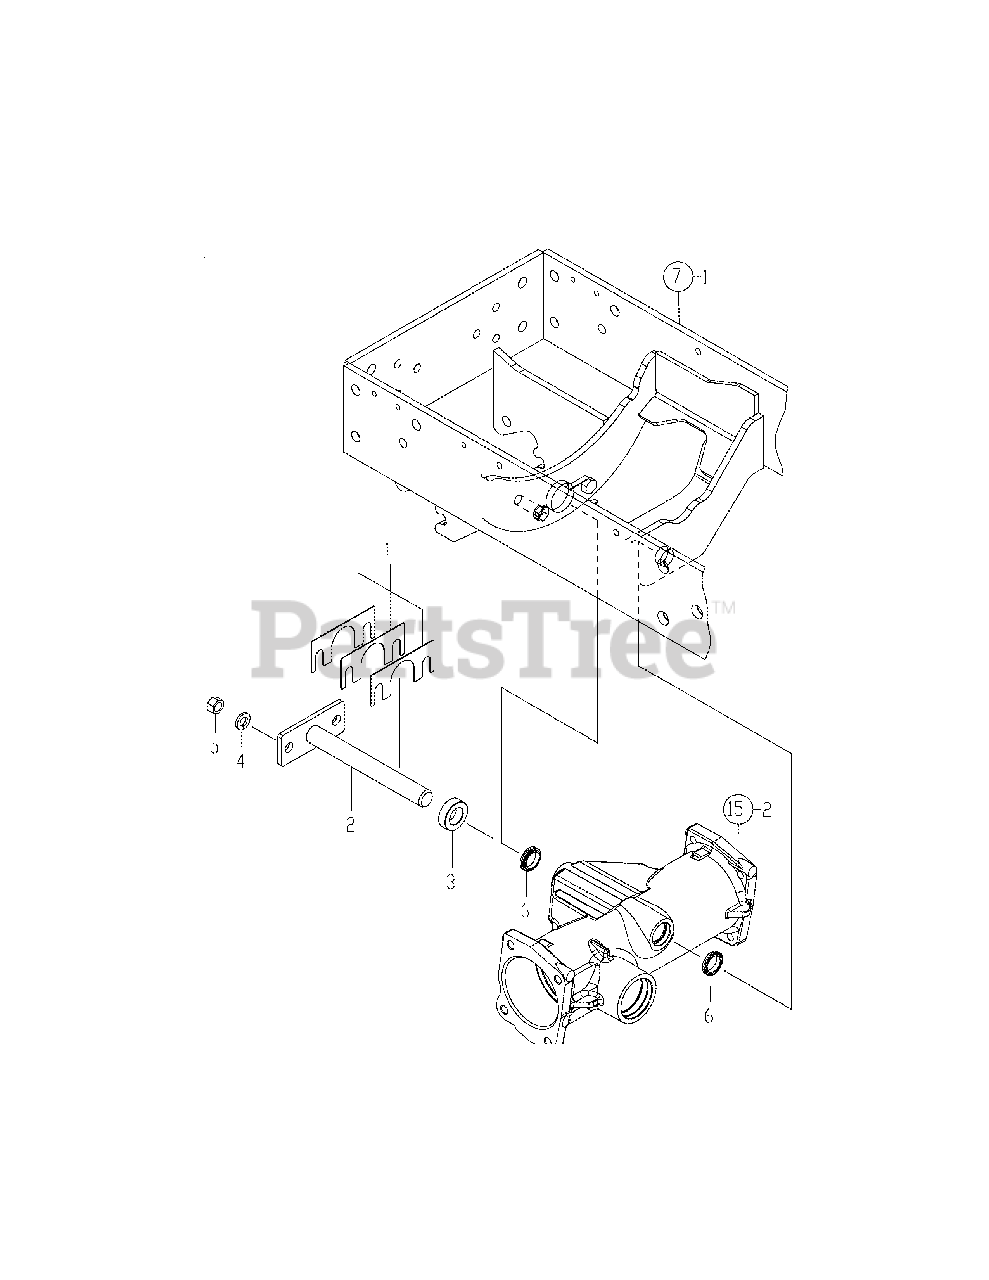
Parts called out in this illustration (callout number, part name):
1	Shim Set, Center Pin
2	Pin Assy, Center
3	Collar,22X38X11.5
3-1	Collar,22X38X12.5
6	Dust Seal 22X30X6
